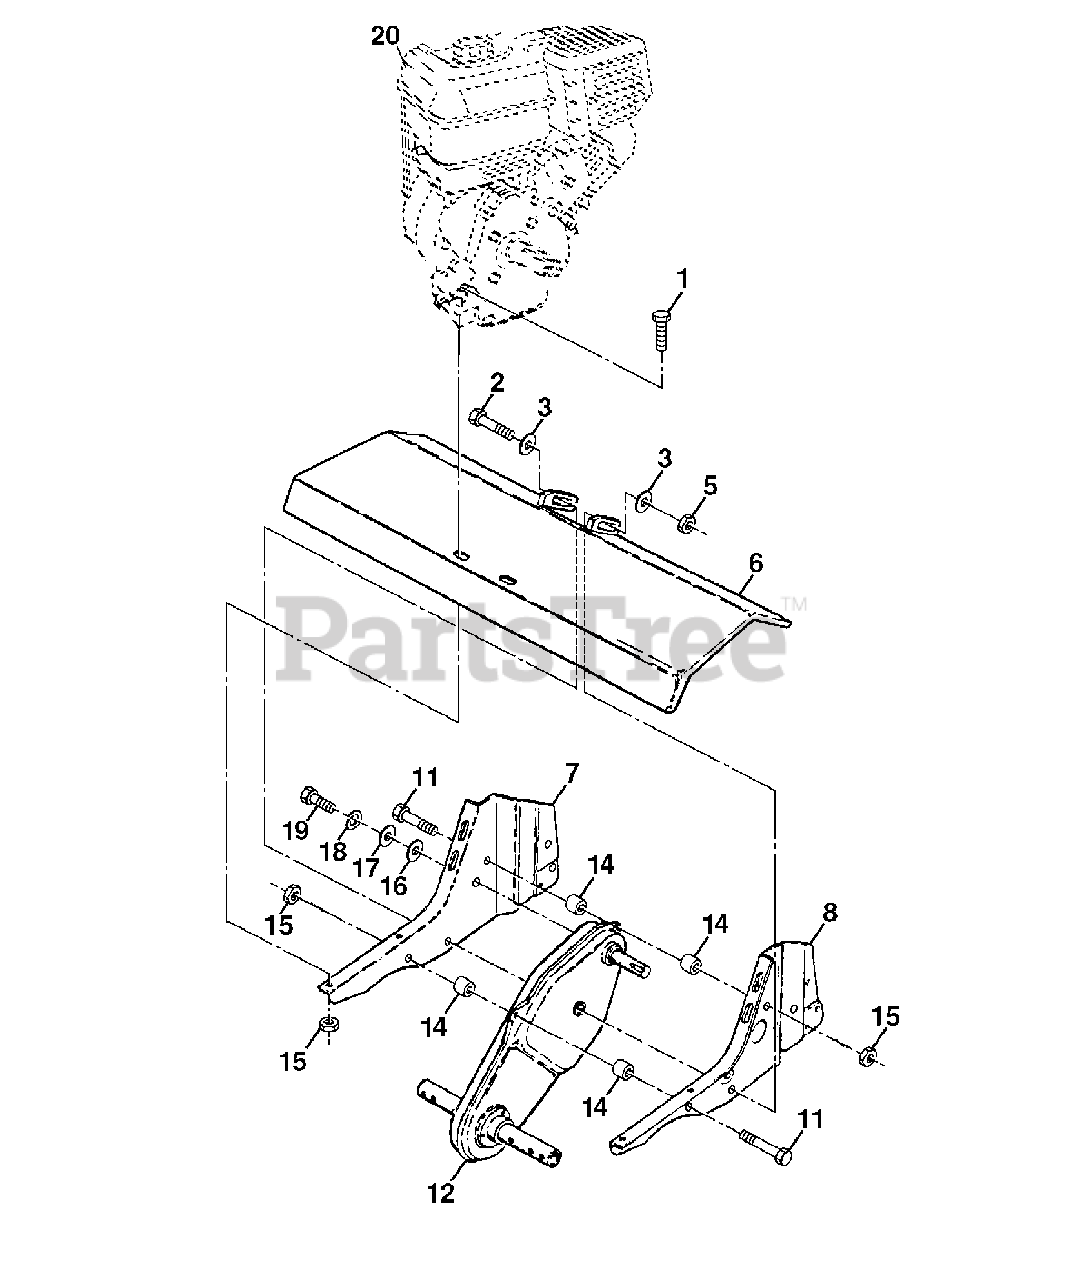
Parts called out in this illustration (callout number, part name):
1	Bolt, Hex 5/16-18 x 1-1/2 Gr. 2
2	Bolt, Hex, Fin 3/8-16 x 3-1/4
3	Washer 13/32 x 13/16 x 11
5	Locknut, Hex, w/washer 3/8-16
6	Shield, Tine
7	Bracket, Engine, R.H.
8	Bracket, Engine, L.H.
9	Washer, Lock 5/16
10	Nut, Hex 5/16-18
11	Bolt, Hex 5/16-18 x 2-3/4
12	Transmission
14	Spacer, Split
15	Nut Lock Hex Flg
16	Washer 9/32 x 7/8 x 12 Ga.
17	Washer 9/32 x 1-1/4 x 16 Ga.
18	Washer, Lock 1/4
19	Bolt, Hex 1/4-28 x 3/4 Gr. 5
